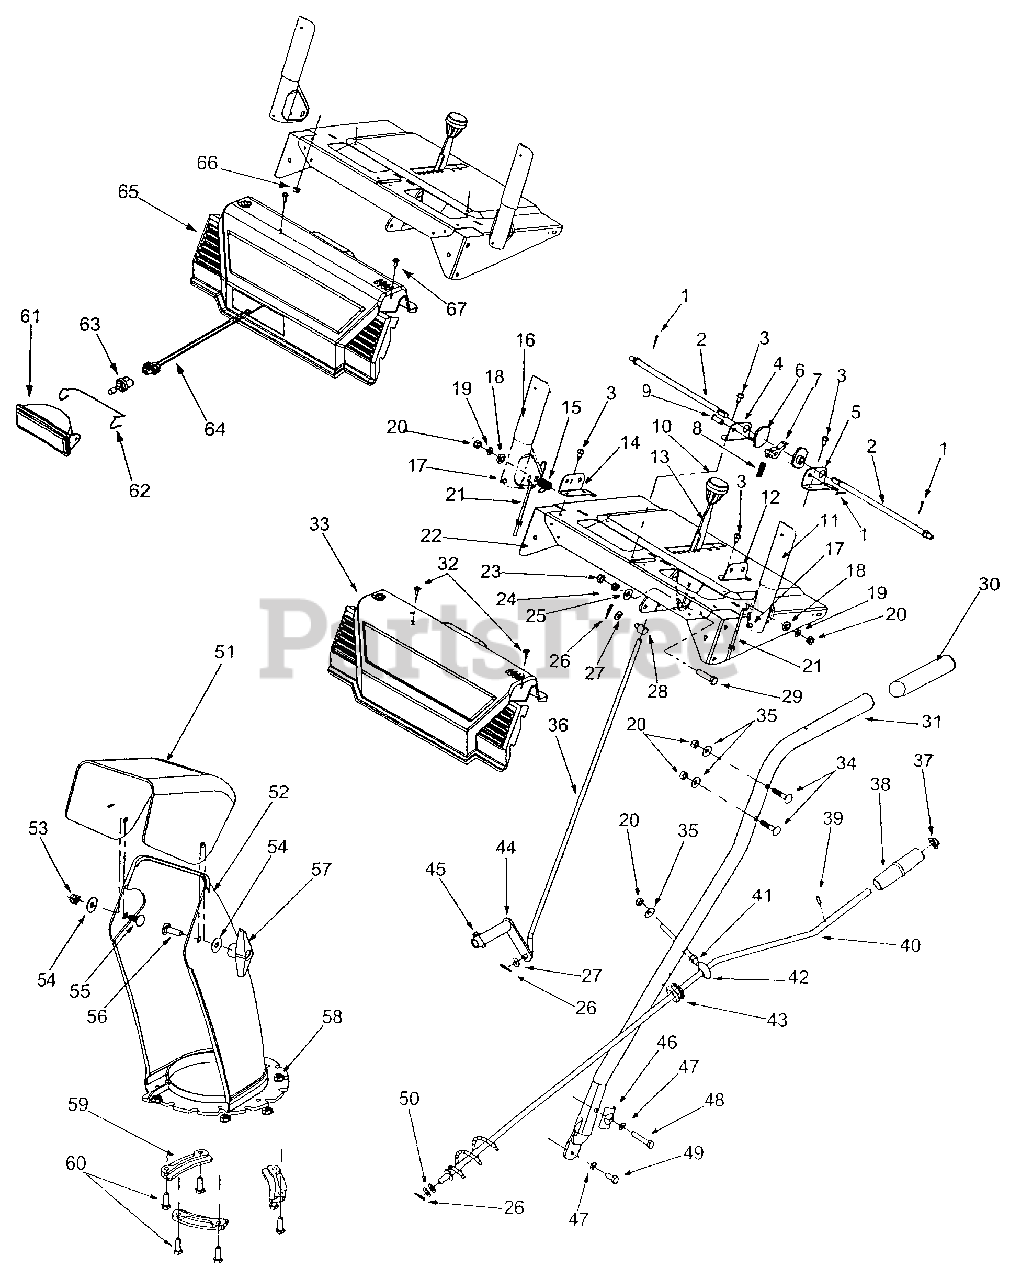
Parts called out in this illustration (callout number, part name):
1	Cotter Pin
3	Hex Washer Screw 1/4-20 x.5
6	Cam Lock Handle
7	Handle Lock Pawl
8	Compression Spring
9	Clevis Pin
10	Knob
11	Handle Assy - LH
15	Torsion Spring
16	Handle Assy - RH
17	Rubber Bumper
18	Washer
19	Lock Washer 5/16
20	Hex Nut 5/16-18
21	"Z" Fittings For Control Cables
24	Compression Spring
25	Bell Washer
26	Cotter Pin
27	Flat Washer 5/16
28	Ferrule
29	Hex Cap Screw 3/8-24 x 1.50
33	Handle Panel
34	Carriage Bolt 5/16-18 x 1.50
35	Bell Washer.340 ID x .872 OD
36	Shift Rod
37	Push Cap
38	Chute Knob
39	Roll Pin
40	Chute Crank
41	Hex Nut 5/16 - 18
42	Chute Crank Eyebolt
43	Rubber Grommet
45	Hex Washer Screw 1/4-20 x 1.0
46	Handle Tab
47	Lock Washer 5/16
48	Hex Cap Screw 5/16-18 x 1.75
49	Hex Cap Screw 5/16-18 x .75
50	Flat Washer
51	Upper Chute
52	Lower Chute
53	Hex Lock Nut 5/16-18
54	5/16 Washer
55	Carriage Bolt 5/16-18 x .75
56	Carriage Screw 5/16-18 x 1.0
58	Hex Lock Nut 1/4-20
59	Flange Keeper
60	Hex Cap Screw 1/4-20 x .75
61	Lens Housing Assembly
62	Headlight Retaining Wire
63	Halogen Light
64	Light Harness
65	Panel w/light
66	Hex Nut 1/4-20
67	Hex Washer Screw #10-16 x .625
